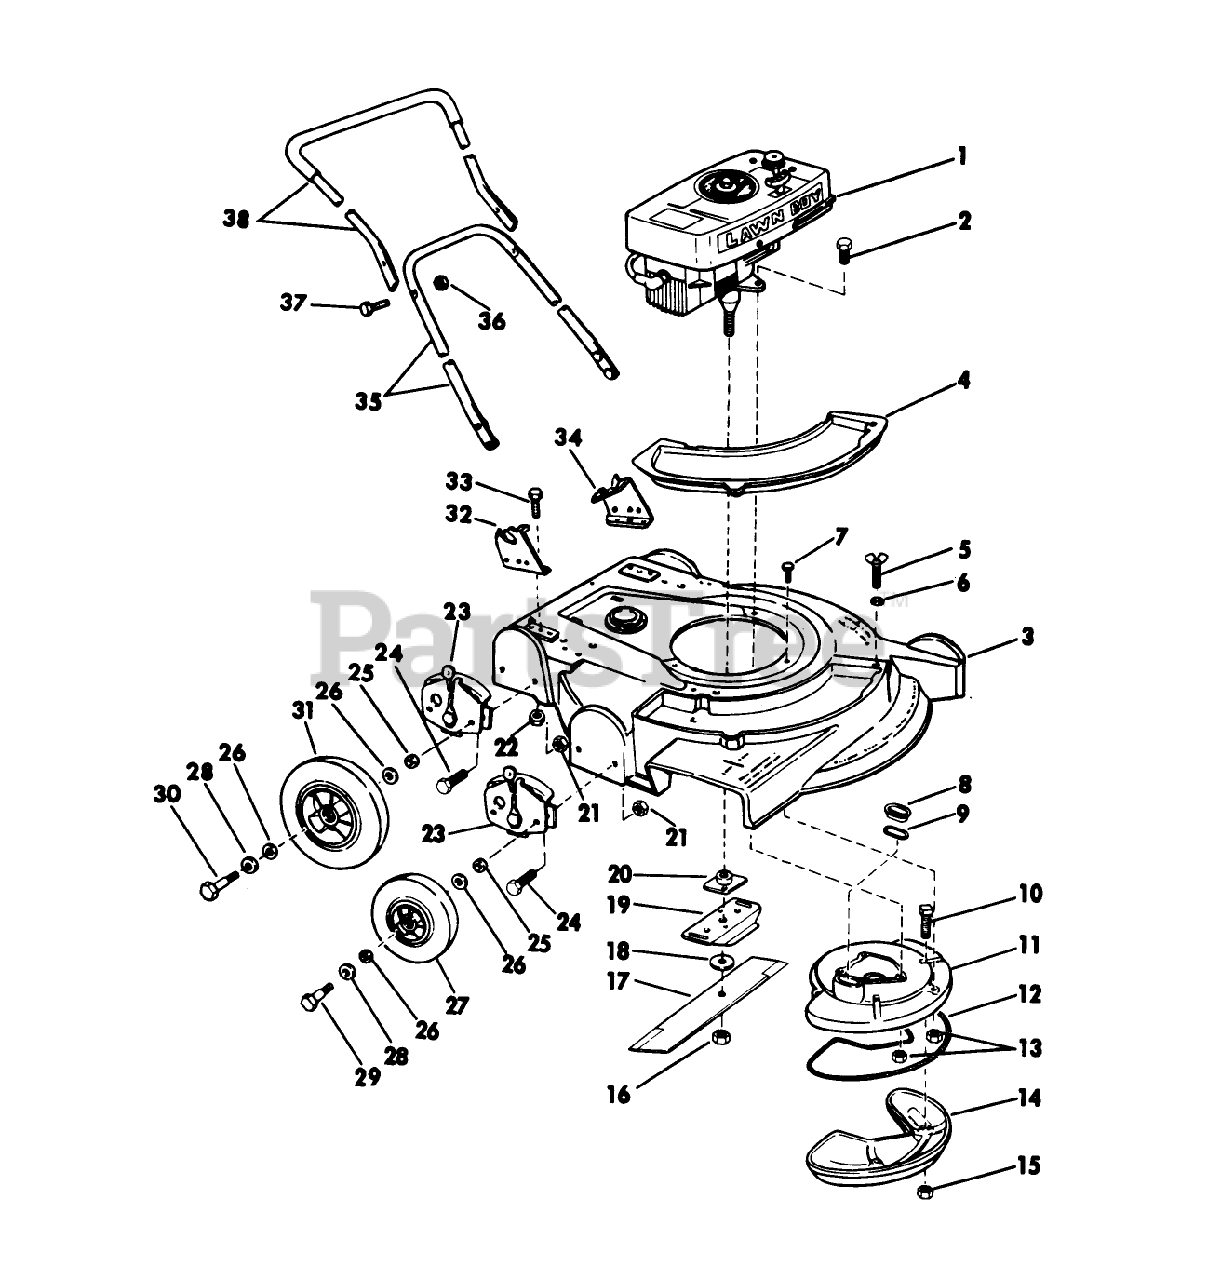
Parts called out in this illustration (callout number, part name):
9	GASKET S
15	LOCKNUT E
16	NUT-BLADE
20	PLATE AND COLLAR ASM
25	WASHER WROUGHT
29	BOLT WHEEL
38	Handle Grip Assy. Top
